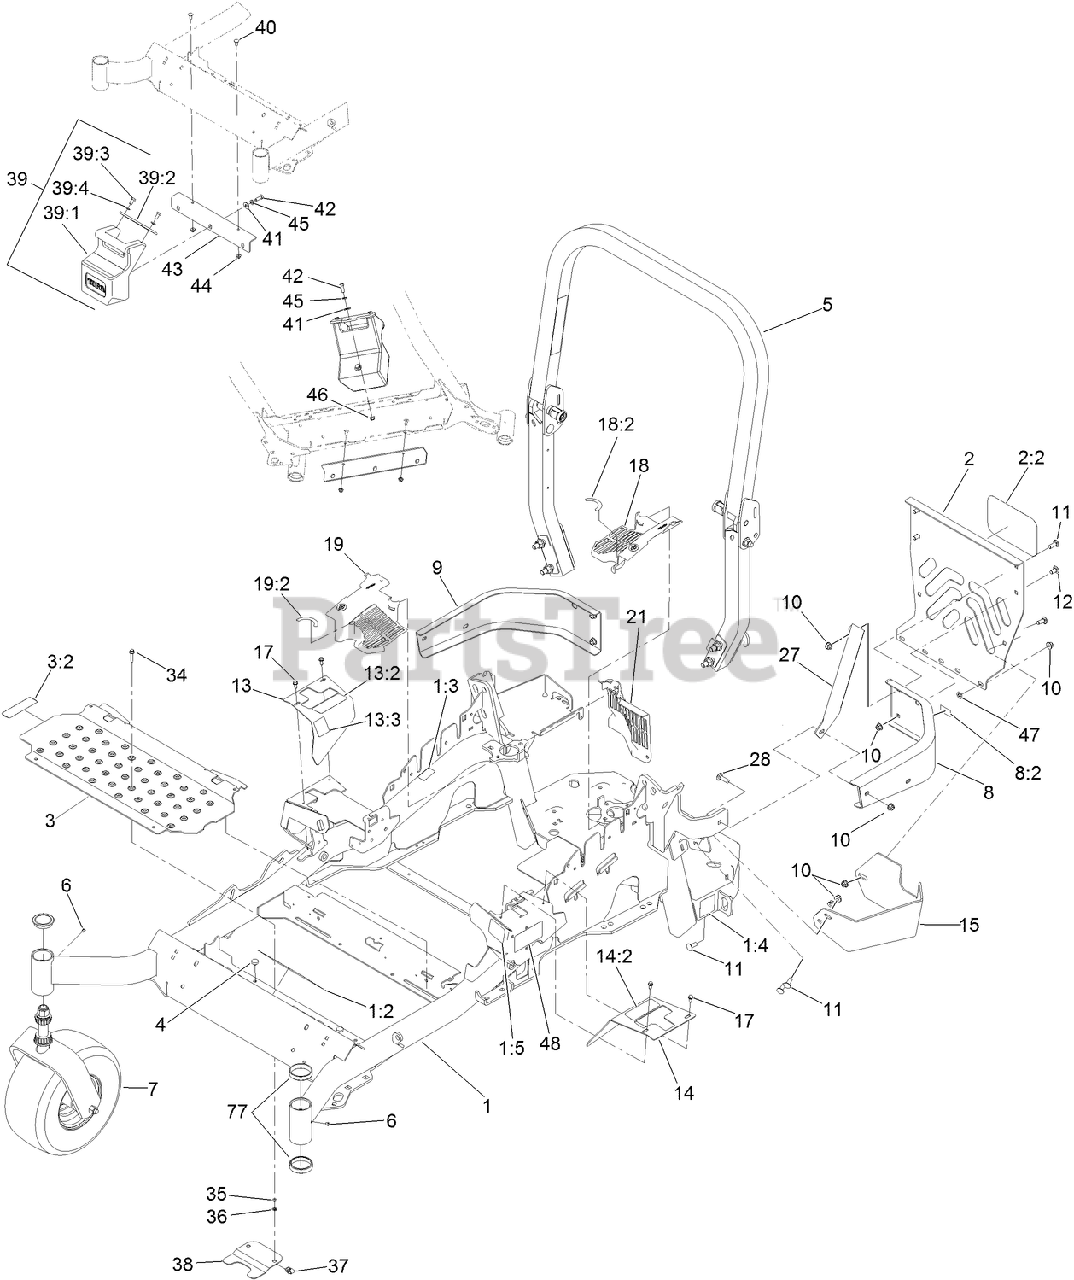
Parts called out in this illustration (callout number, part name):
1	MAIN FRAME ASM
1:2	DECAL-WARNING, SLOPE
1:3	DECAL-WARNING
1:4	DECAL-HAZARD, PINCHED FINGER
1:5	DECAL-FUEL FILL, CE
2	REAR GUARD ASM
2:2	DECAL
3	FLOORPAN ASM
3:2	DECAL-MISSING, COVER
4	BUMPER
5	ROPS ASM
7	Caster Wheel ASM
8	LH REAR BUMPER ASM
8:2	DECAL-WARNING
9	BUMPER-RH
10	NUT-HF, NI
11	SCREW-CARR
12	SCREW-CARR
13	RH MOTION CONTROL COVER ASM
13:2	DECAL-CONTROL, MOTION
13:3	DECAL-PARK BRAKE, CE
14	LH MOTION CONTROL COVER ASM
14:2	DECAL-CONTROL, MOTION
15	GUARD-MUFFLER
17	SCREW-HWH
18	LH HYDRO GUARD ASM
18:2	DECAL-HYDRO OIL
19	RH HYDRO GUARD ASM
19:2	DECAL-HYDRO OIL
21	GUARD-HYDRO, REAR (RH)
28	BOLT-CARR
34	SCREW-HHF
35	WASHER-FLAT
36	NUT-RETAINER
38	ADAPTER-CAPTIVE
39	WEIGHT ASM
39:1	WEIGHT-43 LB
39:2	TAB-SUPPORT, WEIGHT
39:3	SCREW-HH
39:4	WASHER-LOCK
40	SCREW-CARR
41	WASHER-FLAT
42	SCREW-HH
43	BRACKET-MOUNT, WEIGHT
44	NUT-HF, NI
45	WASHER-LOCK
46	NUT-HF, NI
47	NUT-PUSH
77	CUP-BEARING
